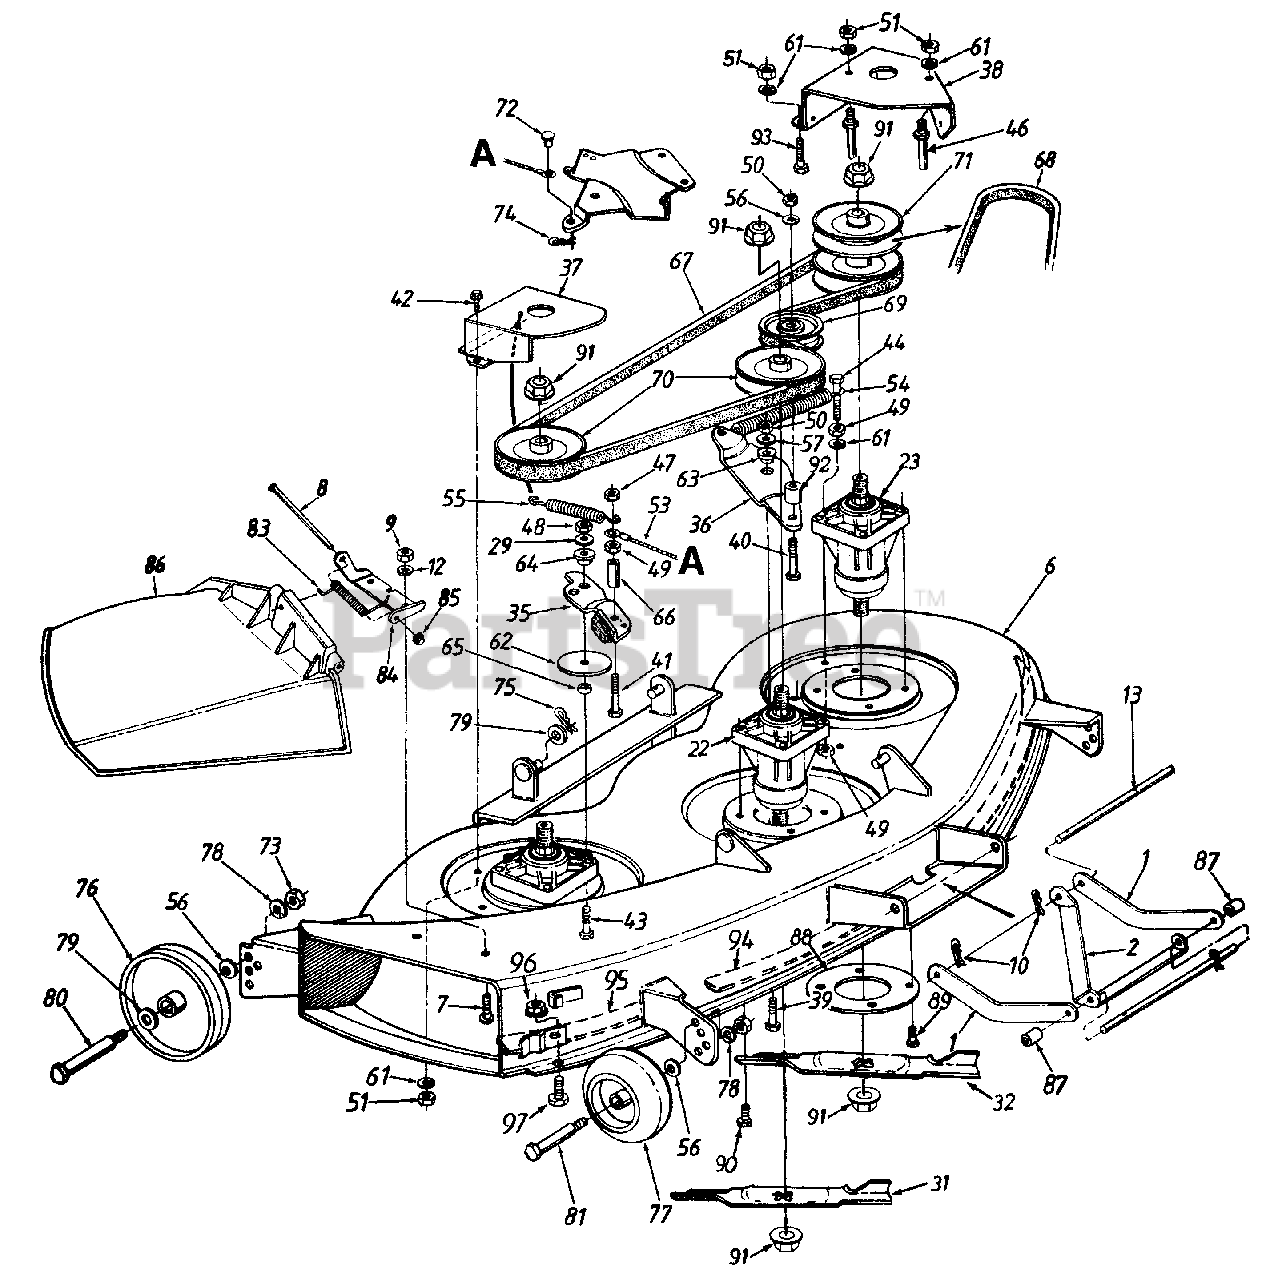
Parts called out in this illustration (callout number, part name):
8	Hinge Pin
9	Hex Nut 1/4-20 Thd. (Gr. 5)
10	Hairpin Clip
12	Bell-Wash. 1/4" I.D.
13	Deck Connecting Rod
22	Spindle Ass'y. (R.H. & Center)
23	Spindle Ass'y. (L.H.)
29	Lock Wash. 5/16" I.D.
31	Blade 14.88" Lg. (Middle)
32	Blade 16.28" Lg. (R.H. & L.H.)
35	Deck Brake Brkt. Ass'y.
36	Idler Bracket
39	Hex Bolt 3/8-24 x 1.0" Lg.
40	Hex Bolt 3/8-24 x 2" Lg.
41	Hex Bolt 1/4-28 x 1.75" Lg.
42	Hex Wash. Hd. Tap-Scr. 1/4-20 x .5" Lg.
43	Hex Bolt 5/16-24 x 1.5" Lg. (Grade 5)
44	Hex Bolt 1/4-28 x 1.5" Lg.
46	Belt Guard Pin 1/4" Dia.
47	Hex Cent. L-Nut 1/4-28 Thd.
48	Hex Nut 5/16-24 Thd.
49	Hex Nut 1/4-28 Thd.
50	Hex Nut 3/8-24 Thd.
51	Hex Nut 1/4-20 Thd. (Gr. 5)
53	Brake Cable Ass'y.
54	Extension Spring 6.17" Lg.
55	Extension Spring 3.97" Lg.
56	Bell-Wash. .38" I.D. x .88" O.D.
57	Bell-Wash. .39" I.D. x 1.13" O.D.
61	L-Wash. 1/4" I.D.
62	Fl-Wash. 5/16" I.D. x 3" O.D.
63	Shld. Spacer .625" I.D.
64	Shld. Spacer
65	Spacer.34" I.D.
66	Spacer .326" I.D.
67	V-Belt
68	V-Belt
69	Fl-Idler Pulley 3.5" O.D.
70	Pulley 5.0" Dia.
71	Double Pulley 5.0" Dia.
72	Clevis Pin 1/4" Dia. x .53" Lg.
73	Hex Nut 3/8-16 Thd.
74	Intern. Cotter Pin 5/16" Dia.
75	Intern. Cotter Pin 3/8 Dia.
76	Deck Wheel 5" Dia.
77	Deck Wheel w/Insert 5" Dia.
78	L-Wash. 3/8" I.D.
79	Fl-Wash. .531" I.D.
80	Shoulder Bolt .498" Dia. x 1.64" Lg.
81	Shoulder Bolt
83	Torsion Spring
84	Hinge Mtg. Brkt.
85	Push Nut
86	Chute Ass'y. Comp.
87	Spacer 5/8" I.D. x 7/8" O.D.
90	Hex Wash. Hd. Scr. 5/16-18 x .75" Lg.
91	i Hex Flange Nut 5/8-18 Thd.
92	Spacer .38" I.D.
93	Hex Bolt 1/4-20 x .5" Lg.
96	Hex Sems Nut 1/4-20 Thd.
97	Carriage Bolt 1/4-20 x .5" Lg.
